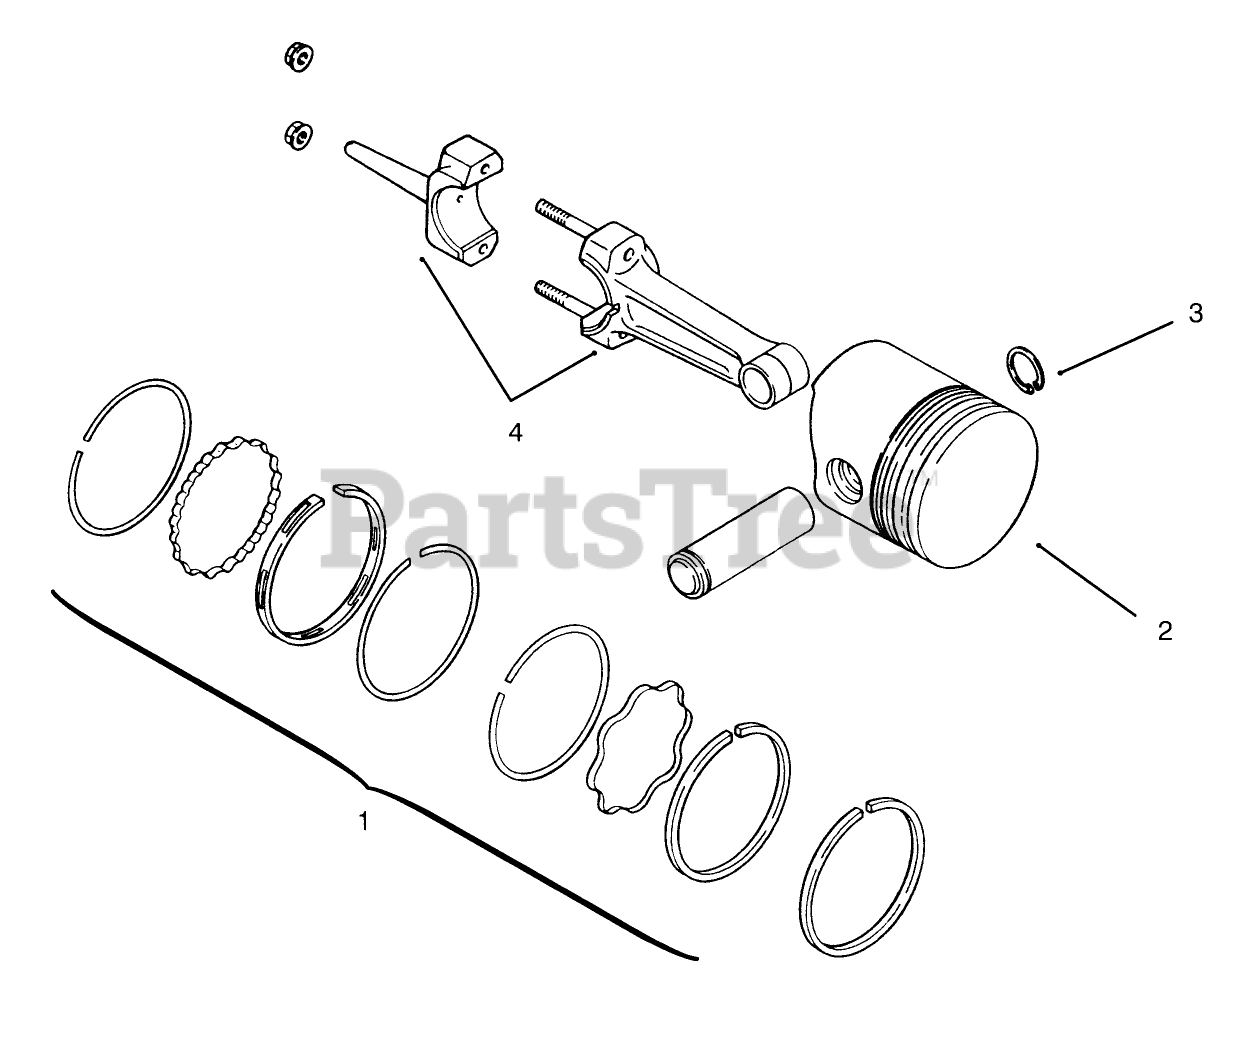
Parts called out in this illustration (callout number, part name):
1	KOHLER 47-108-01
2	KOHLER 47-874-16
3	KOHLER 47-018-01
4	KOHLER 45-067-24
